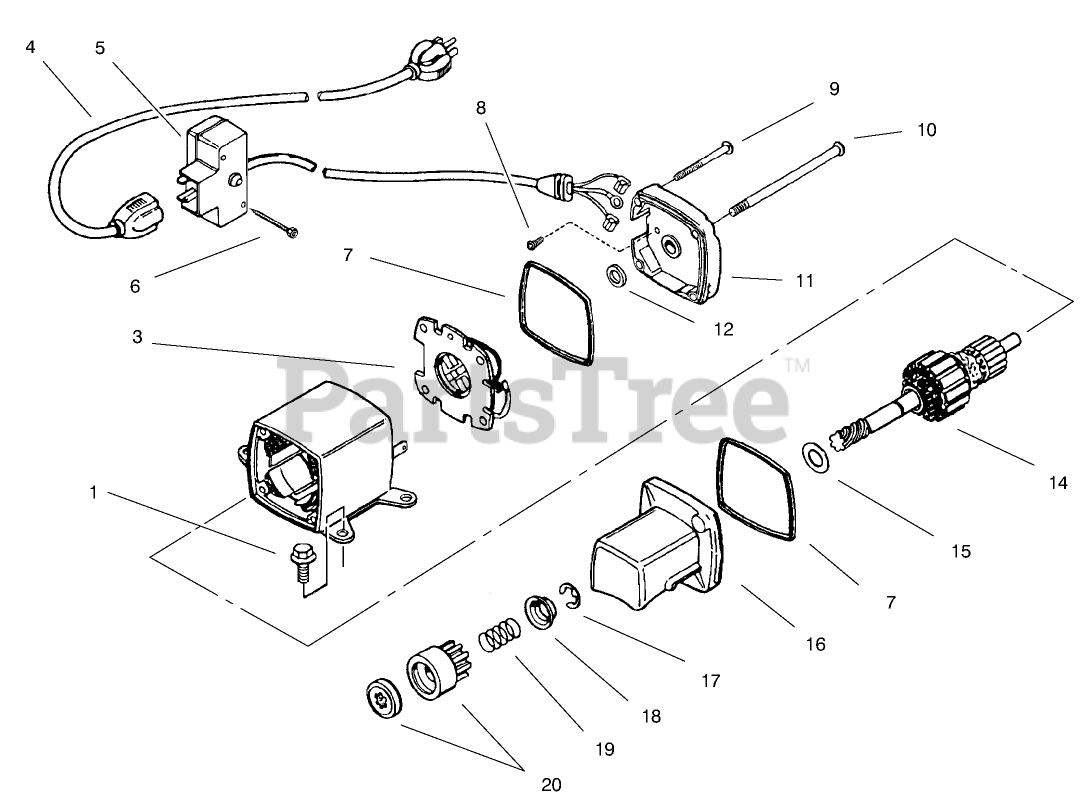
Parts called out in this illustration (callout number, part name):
1	Screw (T-30, 1/4-20 x 23/32)
3	Brush Card ASM
4	Cord-Extension (10-6)
5	Box Assembly-Switch (Incl. Ref. #26)
6	Screw
7	O-Ring
8	Screw-Ground
9	Screw-Ground
10	Bolt-Case
11	Cap Assembly (Incl. Ref. #7)
12	Washer-Thrust
14	Armature
15	Washer-Thrust
16	Cap Assembly (Incl. Ref. #7)
17	Retainer-Ring
18	Retainer-Spring
19	Spring-Anti Drift
20	Nut Gear
